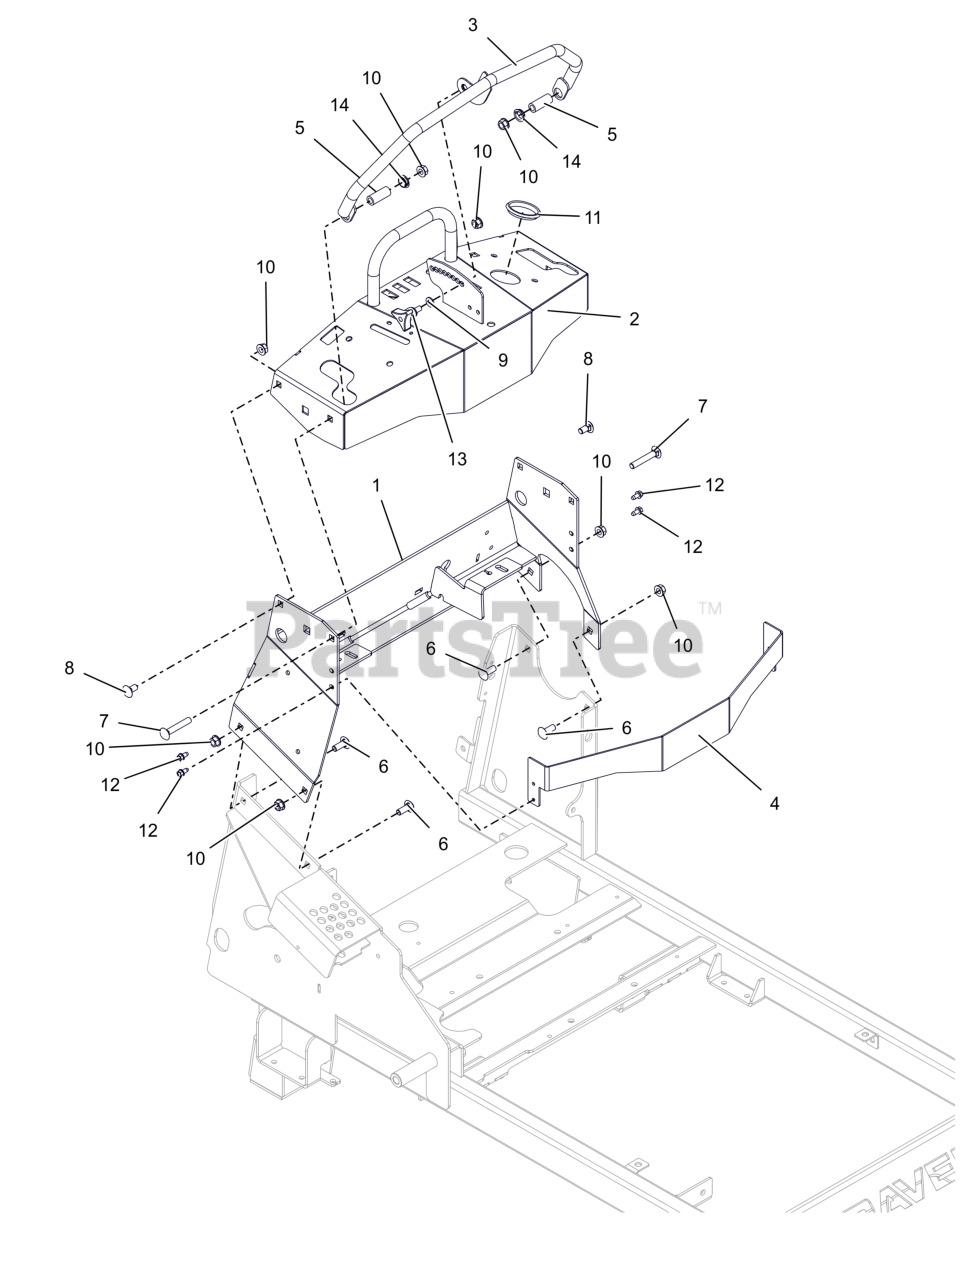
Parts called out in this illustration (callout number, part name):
1	KIT,PROSTANCE TOWER WITH DECAL
2	WLDMT, DASH (RED)
3	WLDMT, CRUISE BAR
4	PLATE, DASH - ACCENT (BLACK)
5	SPACER, .375 X .625 X 1.54
6	BLT,RHSSN .38-16X1.00 G5 ZCC
7	BLT,RHSN .38-16X2.25 G5 ZCC
8	BLT, RHSN .38-16X.750 G5 ZCC
9	WSHR,FLT .344X.688X.065 ZCC
10	NUT-LK-CTR-FLG .375-16 GF ZCC
11	GROMMET, RUBBER 1.89 ID
12	SCR-TAP .25-20X.50 HWH ZCC
13	KNOB,WING STUD 5/16-18 X .75
14	BUSHING, POLYLINER-.63 SNAPIN
